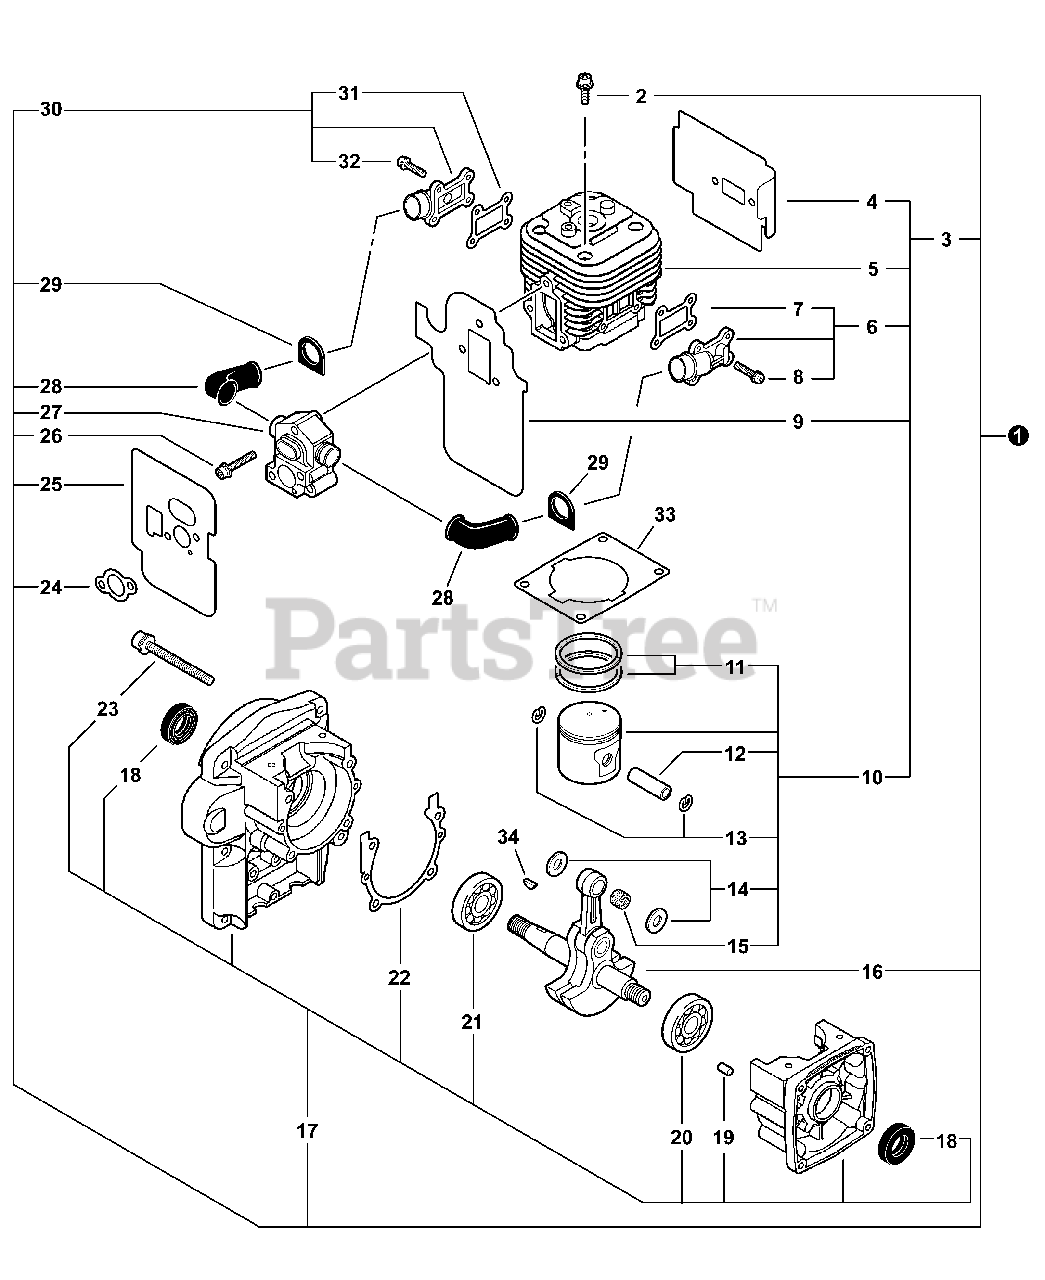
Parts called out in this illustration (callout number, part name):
1	SHORT BLOCK PB-500 & EB508RT
2	BOLT 5×22
3	CYLINDER/PISTON KIT
4	HEAT SHIELD, EXHAUST
5	CYLINDER
6	REED VALVE KIT (S)
9	GASKET, INTAKE
10	PISTON KIT
16	CRANKSHAFT ASSY
17	CRANKCASE ASSY
18	SEAL, OIL
19	PIN, LOCATING 4×8
20	BEARING, BALL 6202
21	BEARING, BALL 6302 C3
22	GASKET, CRANKCASE
23	BOLT 5×40
24	GASKET, INTAKE
25	GASKET, INTAKE
27	INSULATOR
28	HOSE, AIR
29	GROMMET
30	REED VALVE KIT (M)
31	GASKET, INTAKE
33	GASKET, CYLINDER
34	KEY, WOODRUFF 3×14
